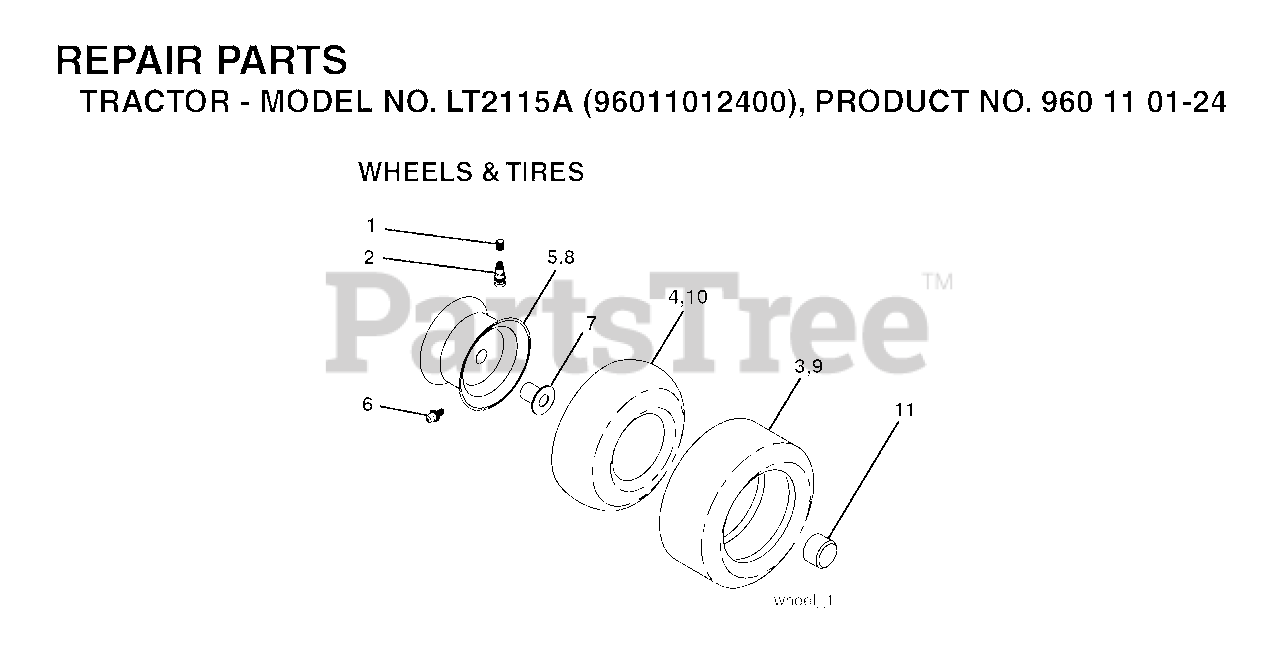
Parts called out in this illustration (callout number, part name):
1	VALVE CAP
2	VALVE STEM LT
3	TIRE HEAVY DUTY
4	TUBE.5.3/4.5/6
5	RIM ASM 6" FRONT SILVER
6	FITTING LT
7	BEARING T
8	RIM ASM 8" REAR SILVER
9	TIRE HEAVY DUTY
10	TUBE
11	CAP, AXLE BLK
